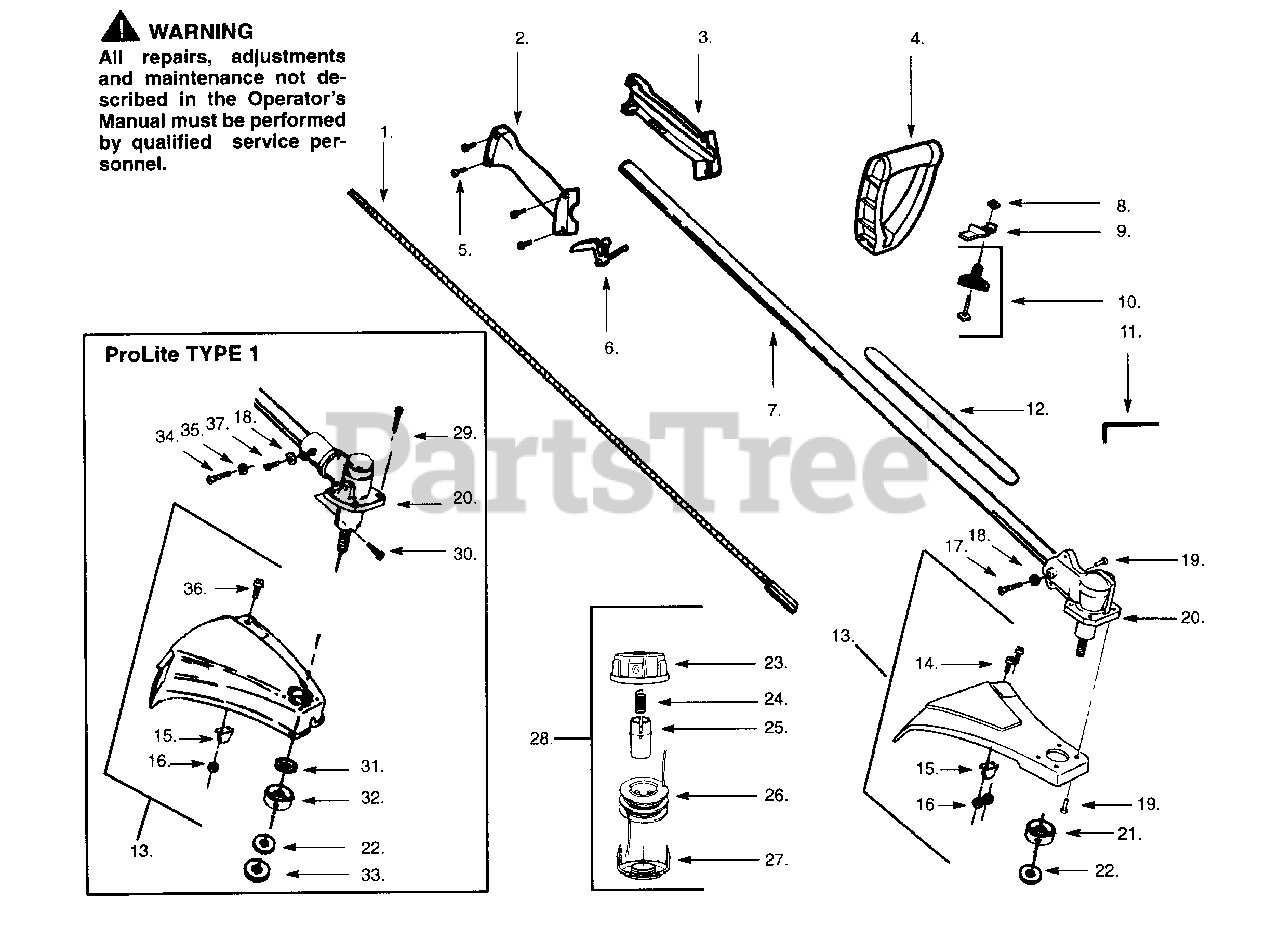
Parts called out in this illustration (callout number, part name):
1	Drive Shaft-52"
2	Throttle Hsg. (Right)
3	Throttle Hsg. (Left)
4	Assist Handle,Cushioned
5	Screw-Throttle Hsg.
6	Trigger Lever
7	Drive Shaft Hsg.
8	Nut-Handle
9	Clamp-Handle
10	T-Handle Kit
11	Hex Wrench 5/32
12	Shaft Warning Decal
13	MODEL PROLITE Type 1 (Incl. 15, 16 & 36)
13	MODELS PROLITE Type 2 & XT45 (Inc. 14-16,19)
14	Screw-Line Limiter
15	Line Limiter
16	Locknut-Line Limiter
17	Screw-Gear Box
18	Lockwasher-Gear Box
19	Screw-Gear Box/Shield
20	MODEL PROLITE Type 1
20	MODELS PROLITE Type 2 & XT45
21	Dust Cup
22	Grass Washer
23	Hub Ass'y
25	Release Button
26	Spool w/ Line
28	Cutting Head Ass'y(Incl. 23-27)
29	Screw-Gear Box/Shield
30	Screw-Grease Refill
32	Dust Cup
34	Screw-Pinch Clamp
35	Lockwasher-Pinch Clamp
36	Screw-Line Limiter
37	Screw-Locating
